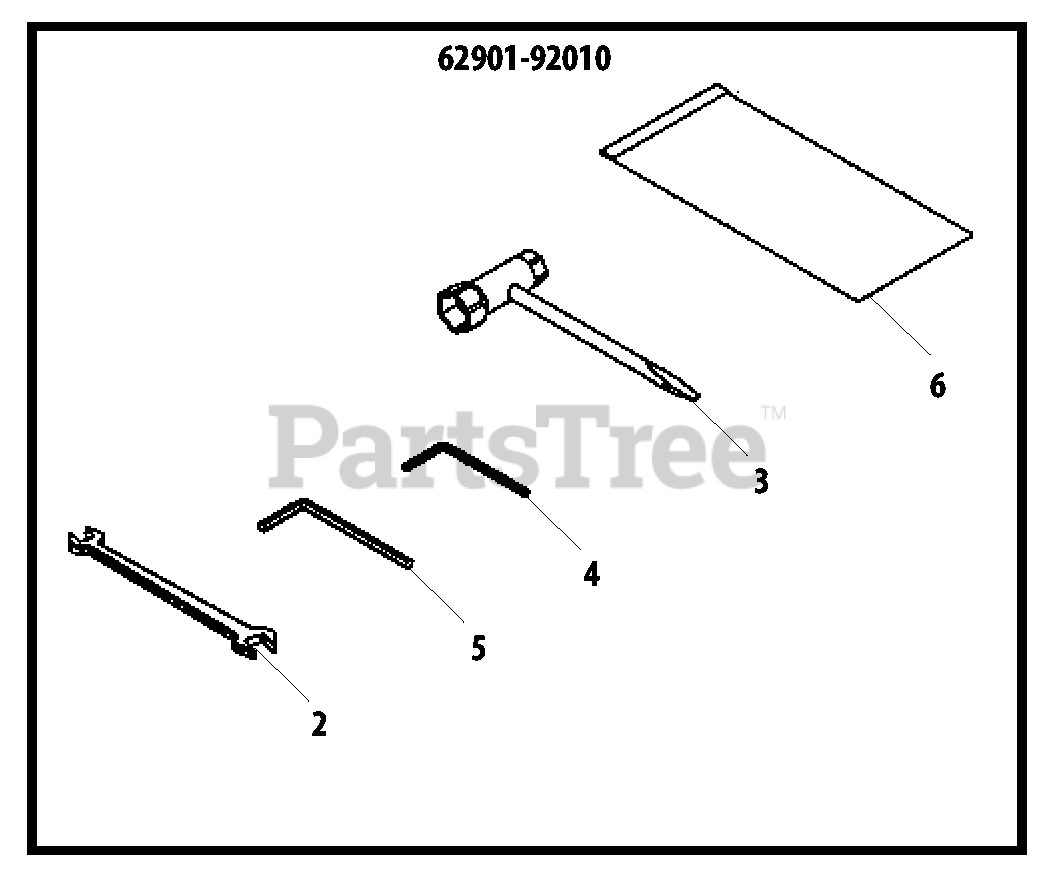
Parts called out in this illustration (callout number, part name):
2	SPANNER 8×10
3	T-WRENCH 16×13
4	WRENCH, ALLEN 3 MM
5	WRENCH, ALLEN 4 MM
6	BAG, TOOL
62901-92010	TOOL KIT, SERVICE
